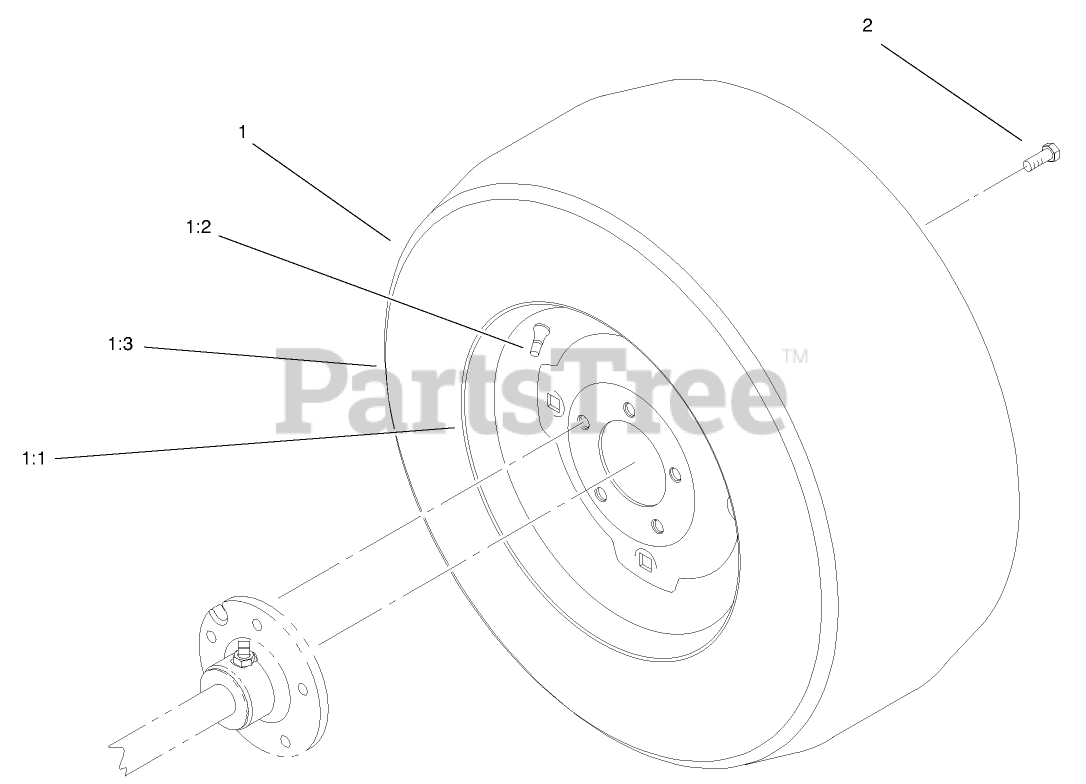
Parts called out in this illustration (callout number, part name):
1	ASM - WHEEL & TIRE
1	ASM - WHEEL/TIRE,REAR
1:1	TIRE - 23 X 10.50-12
1:1	TIRE - 23 X 10.5-12
1:2	VALVE
1:3	RIM ASM
2	BOLT-LUG
